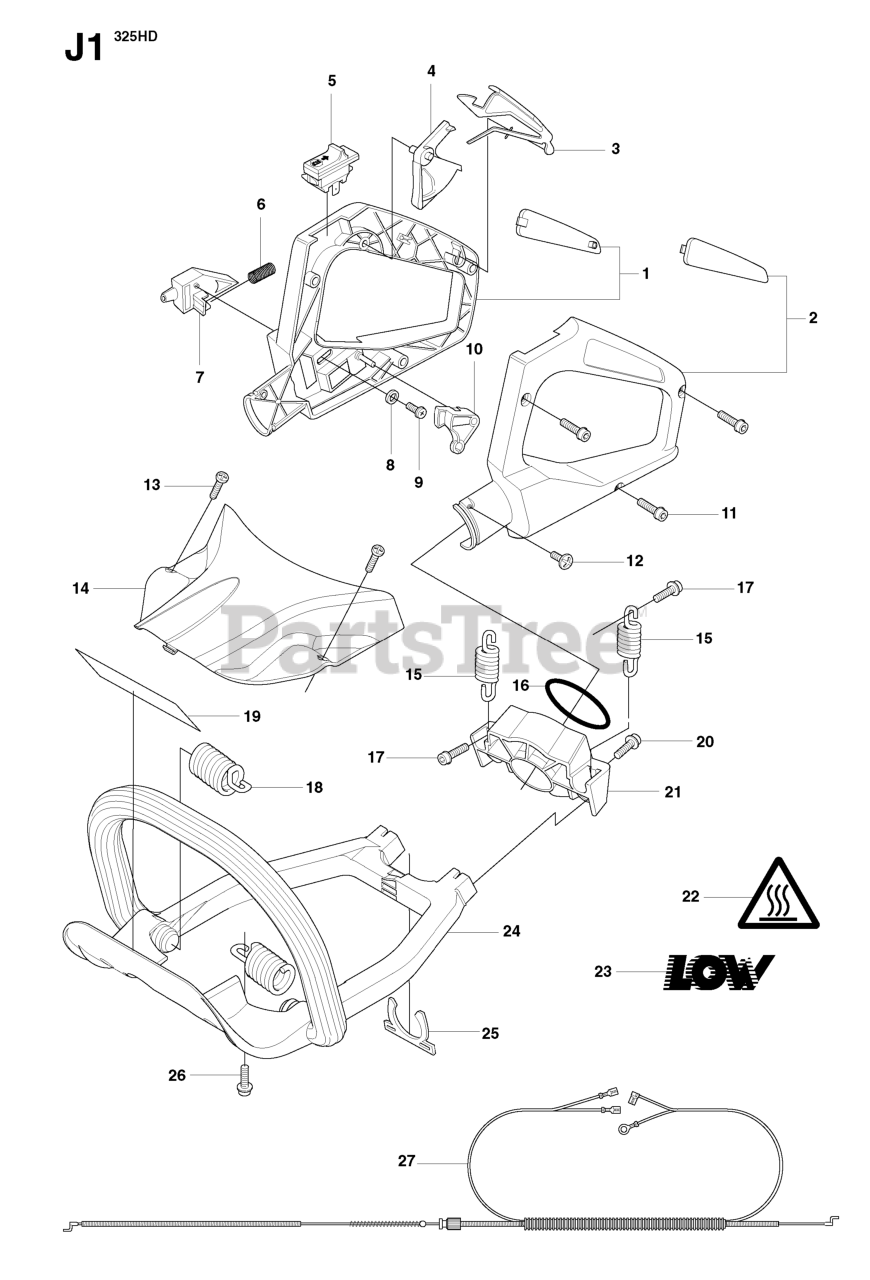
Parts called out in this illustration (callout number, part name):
1	REAR HANDLE COMPLETE
2	HANDLE PART
3	THROTTLE LOCK
4	THROTTLE TRIGGER
5	STOP BUTTON
14	HEAT PROTECTOR EXHAUST PIPE
15	VIBRATION ABSORBER
18	VIBRATION ABSORBER
27	CABLE ASSY
